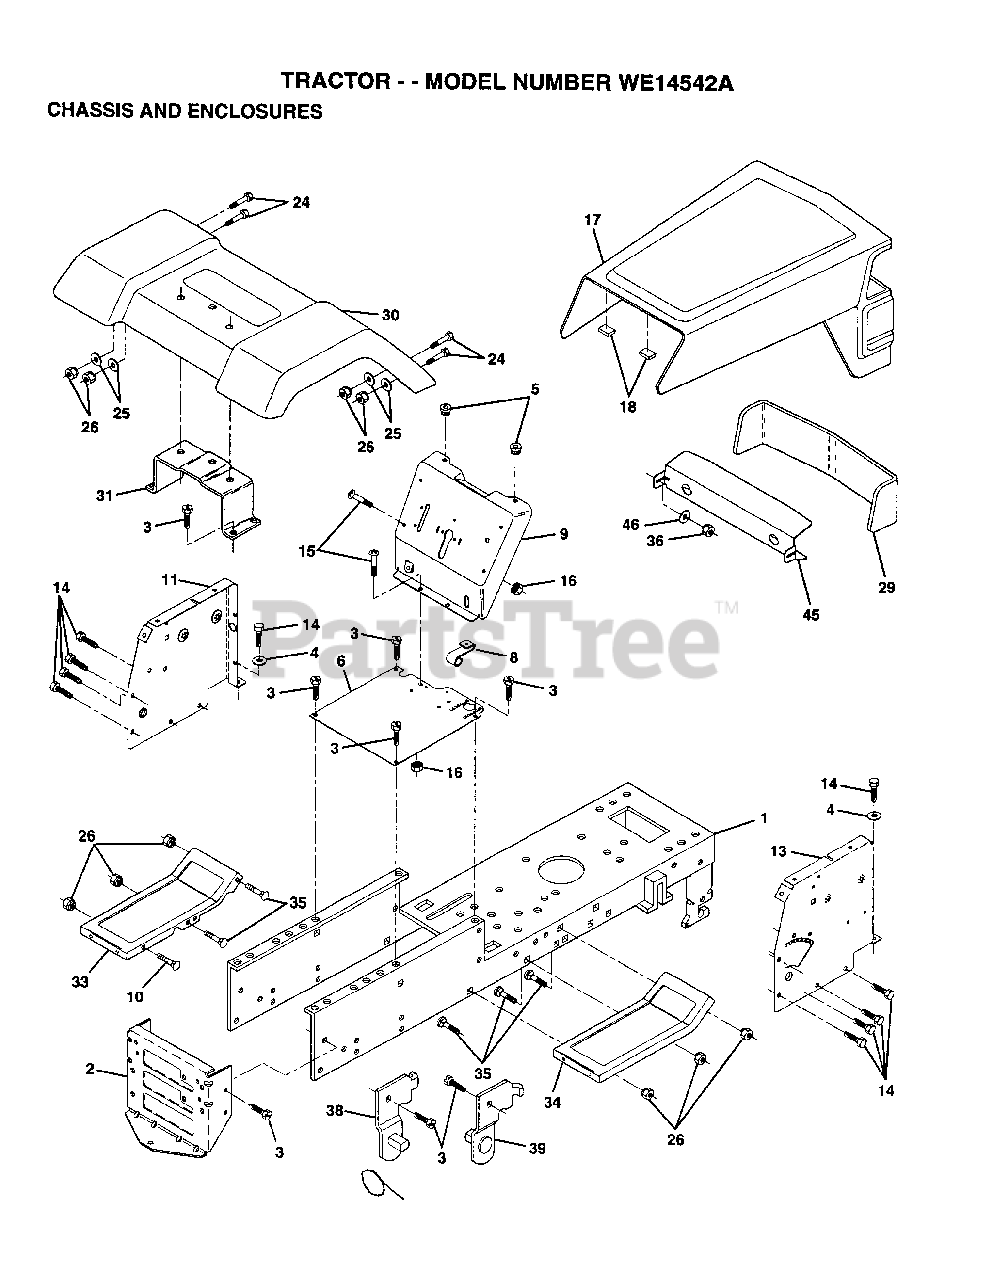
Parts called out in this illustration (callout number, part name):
3	SCREW
4	WASHER
8	"CLIP,INSULATOR"
9	DASH.SLKSC.LT.1PC
11	PANEL.DASH.LH.
14	SCREW LT
15	SCREW
17	HOOD/GRILLE.ASM.
24	BOLT
25	WASHER
26	NUT
31	BRKT FENDER
33	FOOTREST.LH.LT/GT
34	FOOTREST.RH.LT/GT
35	BOLT
36	PAL NUT LT
38	BRACKET ASM LH
39	BRACKET ASM RH
46	RETAINER
